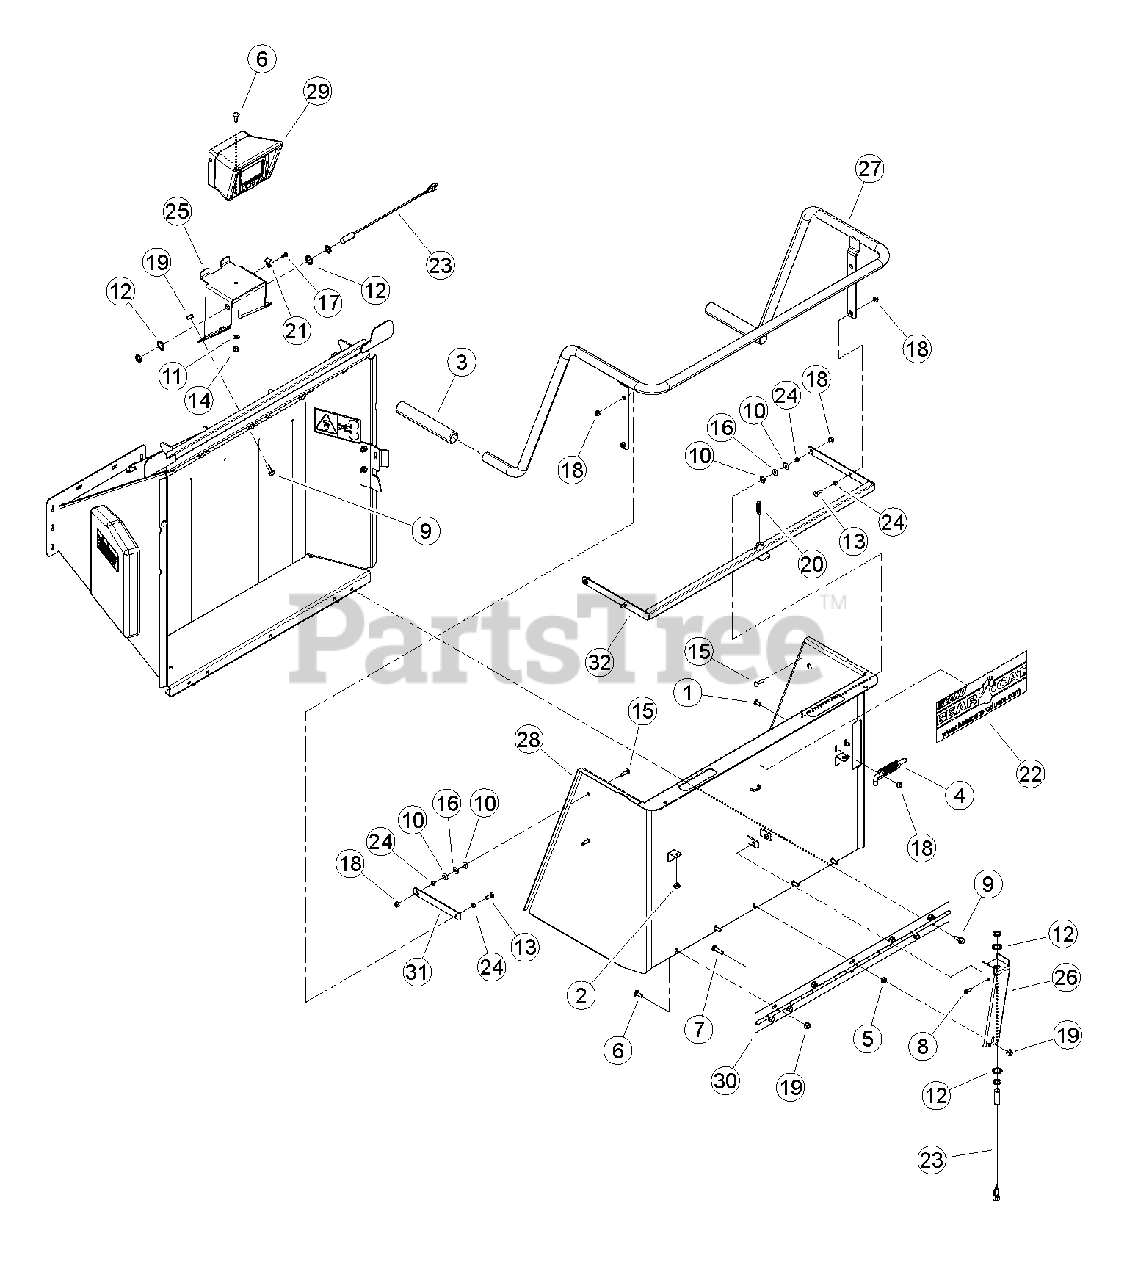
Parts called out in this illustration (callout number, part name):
1	BOLT, 5/16-18 X 3/4 SN GR5 CRG
2	BUMPER, RUBBER
3	GRIP, 1.219 X 10.00
4	LATCH, RH HINGE
5	NUT, 3/8-16 SERRATED FLANGE
6	BOLT, 3/8-16 X 1 GR5 CRG
7	BOLT, 3/8-16 X 1-1/2 GR5 CRG
8	BOLT, 1/4-20 X 3/4 FLANGE GR5 CZP
9	BOLT, 3/8 X 1 FLANGE NC
10	WASHER, 5/16 FLAT
11	WASHER, 3/8 SAE FLAT
12	WASHER, 3/4 INTERNAL LOCK
13	BOLT, 5/16-18 X 1 GR5 CRG
14	NUT, 3/8-16 NE NYLOCK
15	BOLT, 5/16 X 1-1/4 GR5 CRG
16	WASHER, 5/16" ID 7/8" OD NYLON FLAT
17	RIVET, AL BLIND 1/4 X 3/4 DOME HEAD
18	NUT, 5/16-18 NYLOCK FLANGE
19	NUT, 3/8-16 NYLOCK FLANGE
20	SPRING, 1/2 X 2.00 LG
21	CLAMP, CABLE MOUNT
22	DECAL, BEARCAT WEB
23	SENSOR, M18 PROXIMITY (REPLACEMENT PART)
24	SPACER, IDLER PIVOT
25	MOUNT, 6" DDC
26	MOUNT, 6" KNEEBAR PROX SENSOR
27	WELDMENT, KNEEBAR 6"
28	WELDMENT, 6" INFEED TRAY
29	ASSEMBLY, DDC ENCLOSURE
30	HINGE, EXTENSION TRAY
31	LINK, PARALLEL
32	WELDMENT, KNEEBAR PIVOT
